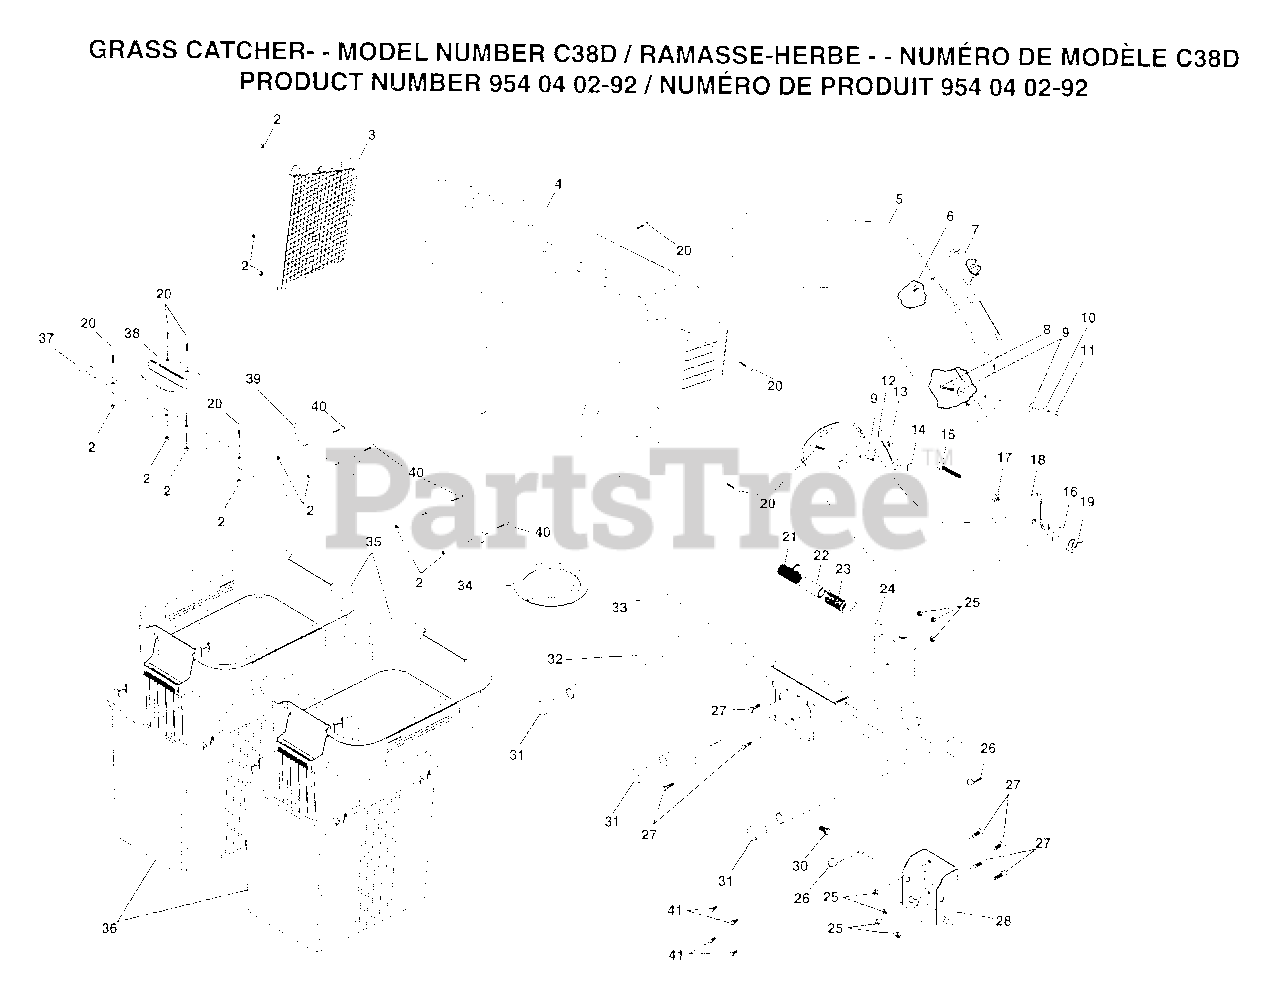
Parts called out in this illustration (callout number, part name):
6	SCREW, SPECIAL #10-14X1/2
9	WASHER 3/16X3/4X16 GA
16	WASHER
17	LOCKNUT
20	SCREW#10-24 X 5/8
27	BOLT, HEX 5/16-18 X 3/4
40	SCREW #10-24 X 1/2
41	SCREW, 5/16-18 X 1/2 HEX, SELF TAPPING
